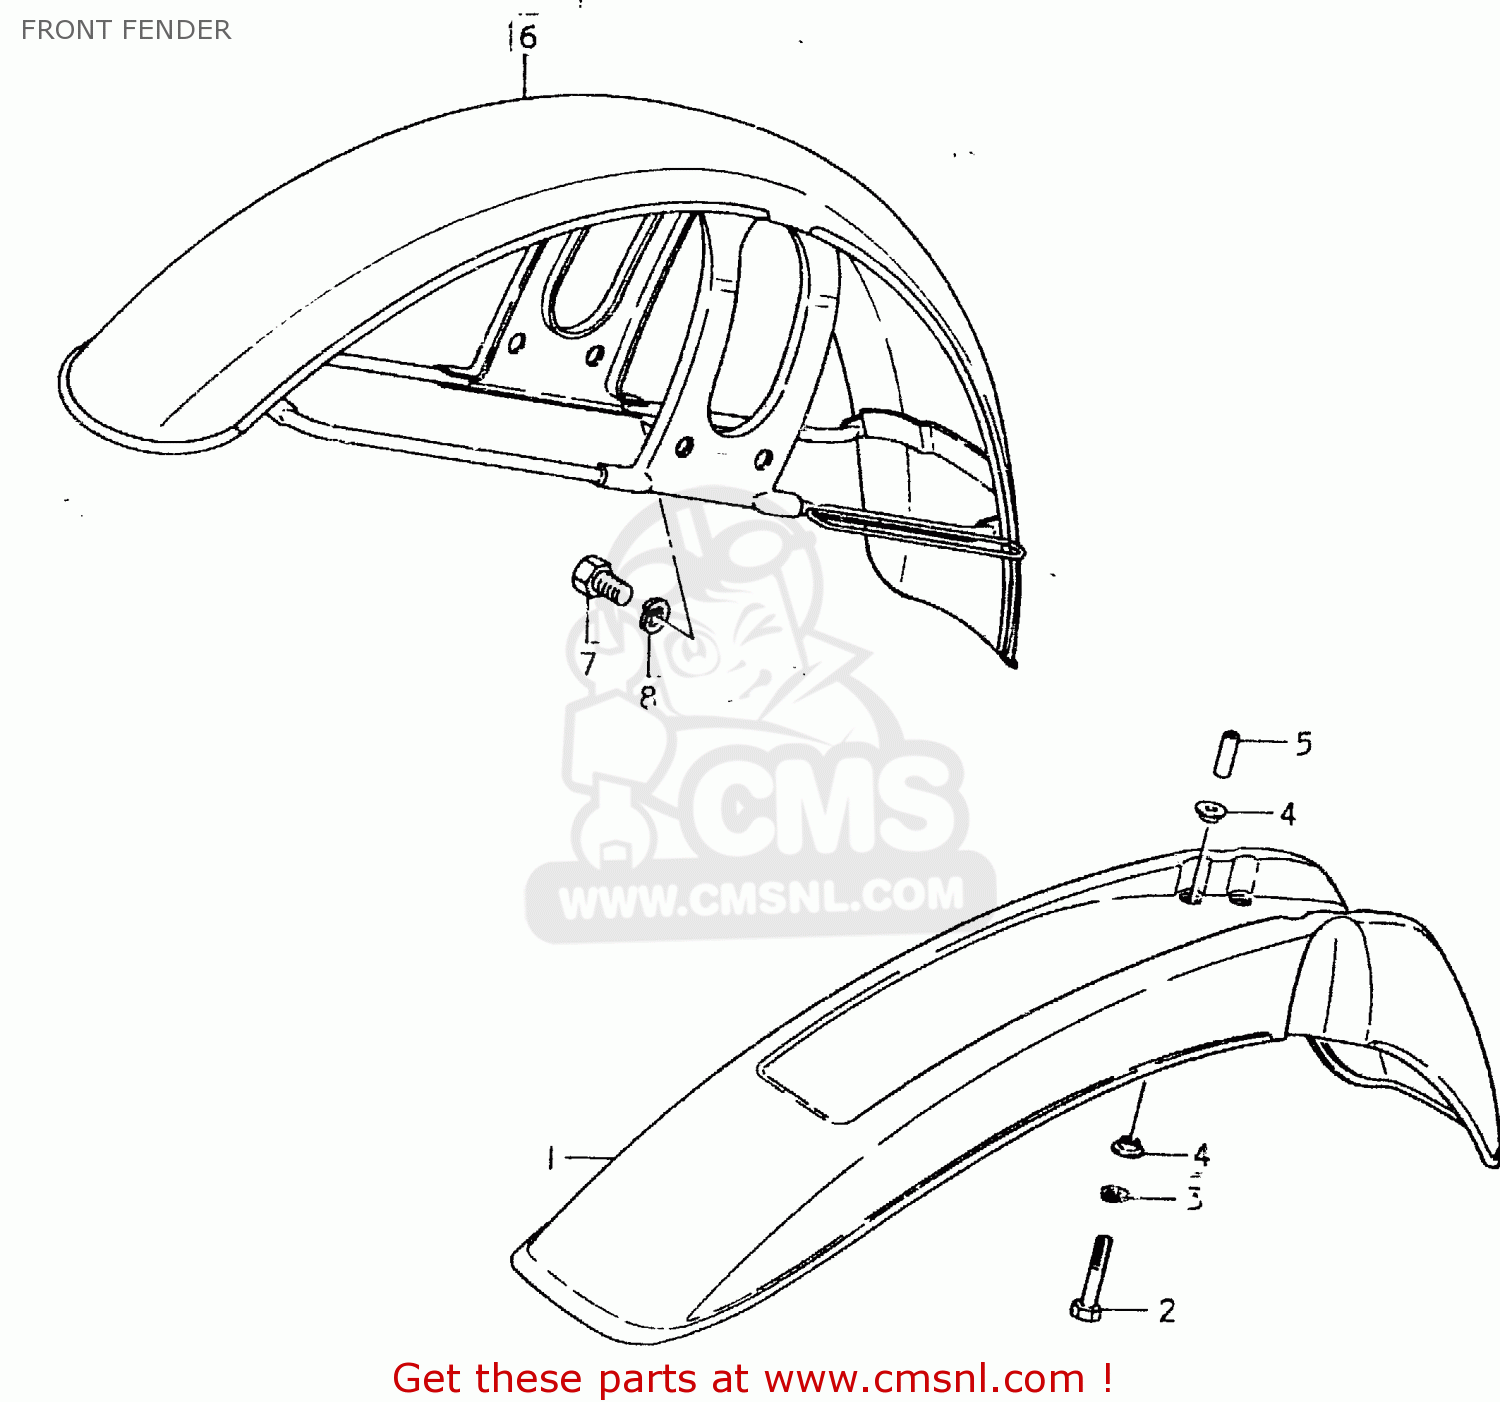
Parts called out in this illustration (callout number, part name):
1	FENDER,FRONT
2	BOLT
3	LOCK WASHER
4	SPACER
5	SPACER (6.8X10X27.4)
6	FENDER,FR
7	BOLT
8	LOCK WASHER
